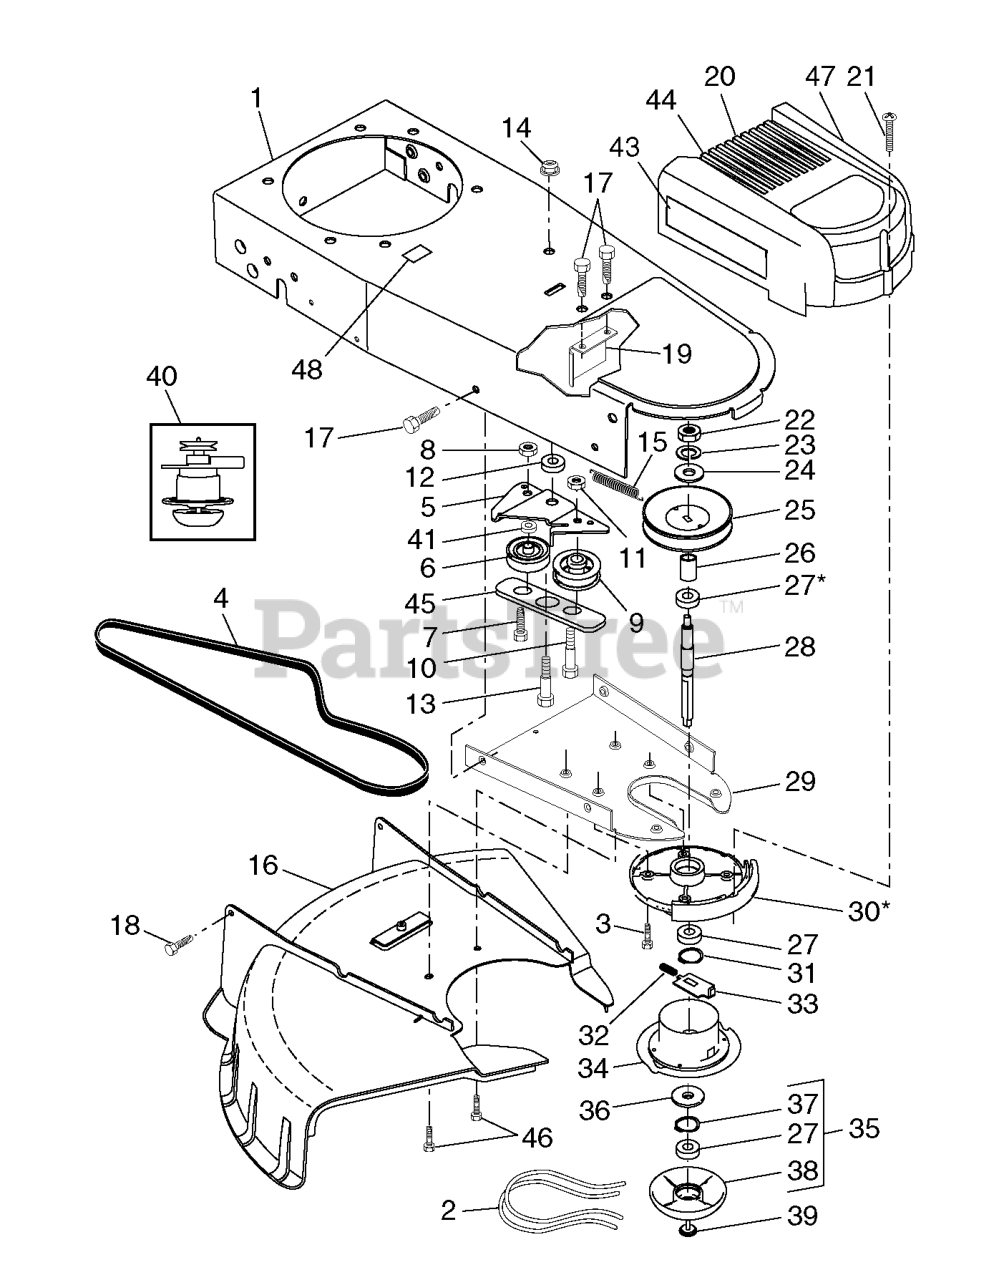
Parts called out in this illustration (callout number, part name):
1	HOUSING.CHASSIS.ASM.MID
2	LINE.BUND.18PC
4	BELT-V.STRING TRIMMER.
5	Idler Bracket, 004 15 String Trimmer
6	PULLEY.V-GROOVE.IDLER
8	LOCKNUT
9	IDLER PULLEY
10	SHOULDER BOLT
11	NUT.CENTERLOCK.5/16-
12	SPACER.IDLER.BRACKET
13	BOLT SHOULDER 3/8 -16X1
14	NUT.HEX.FLANGE.3/8-16.LOCKNUT
15	SPRING.RETURN.WHEELED.TRIMMER
16	Trimmer Deflector, Bottom HW
17	SCREW 14-20 X 5/8
19	KEEPER.BELT.STRING.TRIM.BZP.15
20	COVER.CHASIS.STRIM.POU PRO.E/F
21	SCREW.SLOT.TORX.
22	NUT
24	WASHER, FLAT 3/8
25	PULLEY.SPINDLE.WHEELED.TRIMMER
26	SPACER, PULLEY
27	Spindle Bearing
28	JACKSHAFT.WHEELED.TRIMMER
29	CHASSIS.COVER.BOTTOM.BLACK
30	SPINDLE HOUSING ASSEMBLY
31	RING, RETAINING, EXTERNAL,
32	SPRING.1.5".COMPRESSION
33	PLATE.LOCKING.WHEELED.TRIMMER
34	CARRIER PLATE ASSEMBLY
35	MOW BALL ASSEMBLY
36	COVER, BEARING
37	RING, RETAINING, INTERNAL,
38	MOW BALL
39	BOLT, MOW BALL
40	ASM.ADJUSTABLE.SPINDLE.WHLD.TR
41	SPACER (2 2MC)
43	Instruction Panel Decal
44	DECAL.TRIMMER.WARNING.CE
45	BRACKET.BELT.KEEPER.BLACK
47	DECAL.INSTRUCTION.CE.TRIM.STRG
